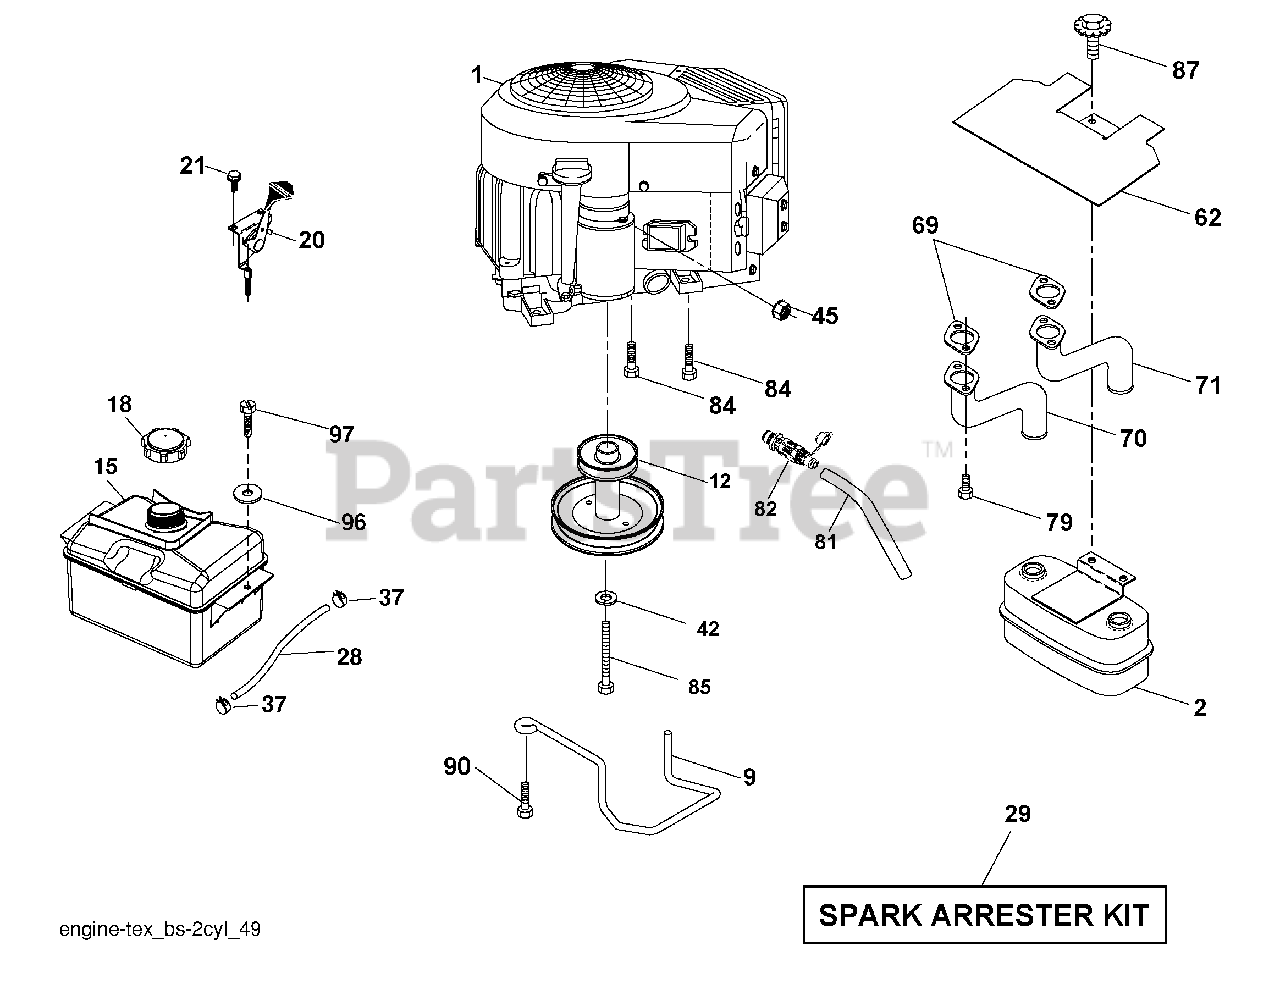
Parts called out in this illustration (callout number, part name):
9	Keeper Belt Engine
12	Pulley Engine
15	Tank Fuel
18	Cap Asm
20	Control Throttle/Choke
21	Screw #10 x 0.750 BOS Thread
28	Fuel Line
29	Spark Arrester Kit
37	Clamp Hose
42	Washer Lock 7/16
45	Nut Keps Hex 1/4-20 unc
62	Shield Heat
70	Exhaust Tube LH
71	Exhaust Tube RH
79	Screw 5/16-18 x 1
81	Tube Drain Oil Easy
82	Valve Drain Oil
84	Screw 3/8-16 x 1/4
85	Bolt Hex 7/16-20 x 4 Gr. 5
87	Bolt 5/16-18 unc x 3/4 w/sems
90	Screw 3/8-16 x 1
96	Washer 9/32 x 7/8 x 16 Ga.
97	Screw 1/4-20 x 3/4
